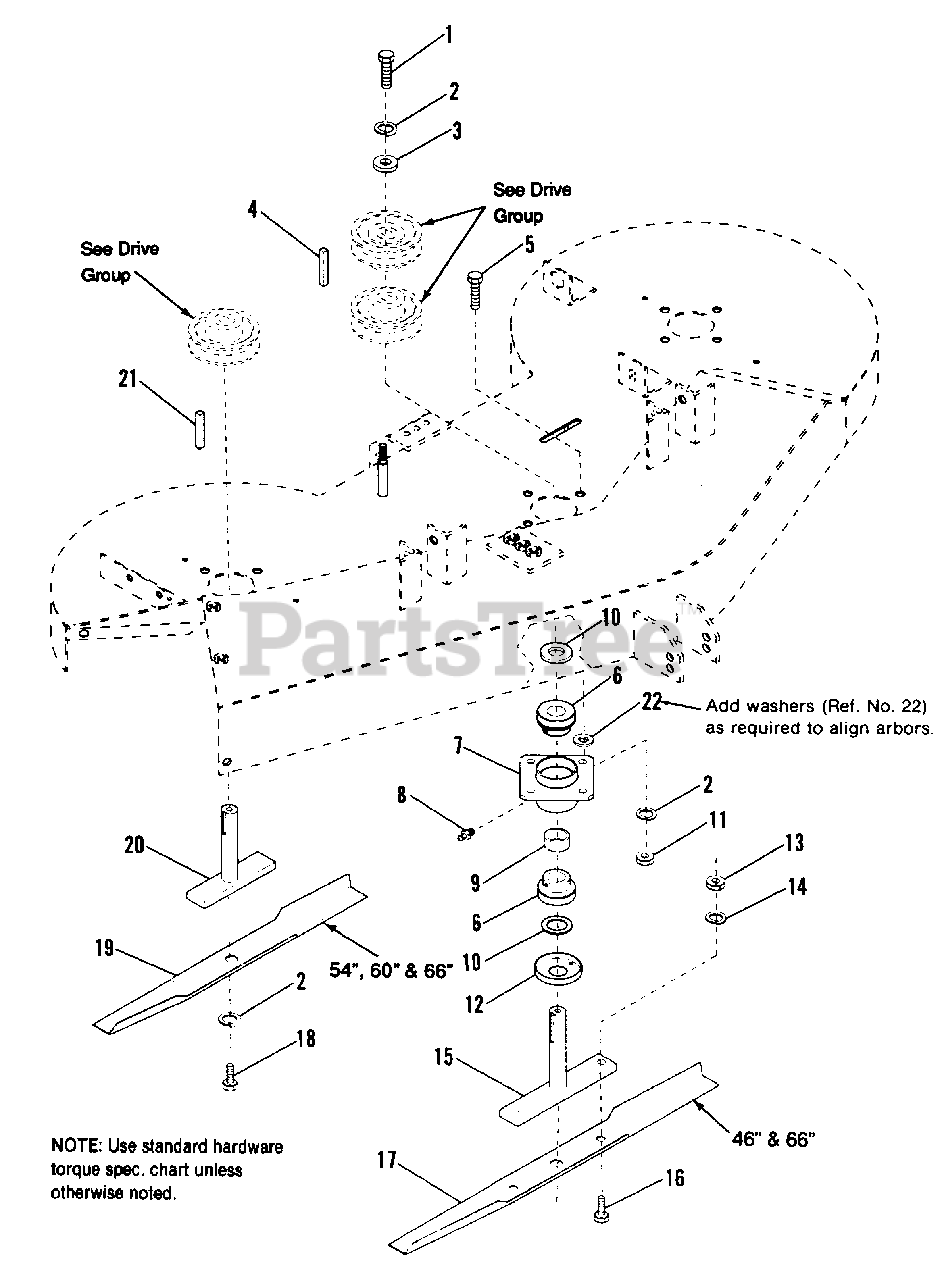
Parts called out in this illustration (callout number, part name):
1	CAPSCREW, Hex, 3/8-24 x 1 (Qty. 2 used on 46" Mower)
2	LOCKWASHER, Spring, 3/8 (46" Mower)
2	LOCKWASHER, Spring, 3/8 (46" Mower) LOCKWASHER, Spring, 3/8 (54" & 60" Mower)
2	LOCKWASHER, Spring, 3/8 (46" Mower) LOCKWASHER, Spring, 3/8 (54" & 60" Mower) LOCKWASHER, Spring, 3/8 (66" Mower)
3	WASHER, Plain (Qty. 2 used on 46" Mower)
4	KEY, Square, 1/4 x 1/4 x 1-3/4
5	CAPSCREW, Hex, 3/8-16 x 1-1/4 (Qt. 8 used on 46" Mower)
6	BEARING, Ball (Qty. 4 used on 46" Mower)
7	HOUSING ASSY., Arbor (Qty. 2 used on 46" Mower)
8	FITTING, Grease (Press Fit) (Qty. 2 used on 46" Mower)
9	SPACER, Bearing (Qty. 2 used on 46" Mower)
10	WASHER, Plain (Qty. 4 used on 46" Mower)
11	NUT, Hex, 3/8-16 (Qty. 8 used on 46" Mower)
12	CUP (Qty. 2 used on 46" Mower)
13	NUT, Hex, 1/2-13 (46" & 66" Mowers only)
14	LOCKWASHER, Spring, 1/2 (46" & 66" Mowers only)
15	ARBOR ASSY., Long (46" & 66" Mowers only)
15	ARBOR ASSY., Long (54" & 60" Mowers only)
16	CAPSCREW, Hex, 1/2-13 x 1-1/4 (46" &66" Mowers only)
17	BLADE, Mower (46" & 66" Mowers only)
18	CAPSCREW, Hex, 3/8-16 x 1 (46" Mower)
18	CAPSCREW, Hex, 3/8-16 x 1 (46" Mower) CAPSCREW, Hex, 3/8-16 x 1 (54" & 60" Mowers)
18	CAPSCREW, Hex, 3/8-16 x 1 (46" Mower) CAPSCREW, Hex, 3/8-16 x 1 (54" & 60" Mowers) CAPSCREW, Hex, 3/8-16 x 1 (66" Mower)
19	BLADE, Mower (54" Mower)
19	BLADE, Mower (46" Mower)
19	BLADE, Mower (46" Mower) BLADE, Mower (60" Mower)
19	BLADE, Mower (46" Mower) BLADE, Mower (60" Mower) BLADE, Mower (66" Mower)
20	ARBOR ASSY., Short (Qty. 1 on 46" Mower)
21	KEY, Square, 1/4 x 1/4 x 1 (Qty. 1 on 46" Mower)
22	WASHER, Plain (Qty. 4 on 46" Mower)
